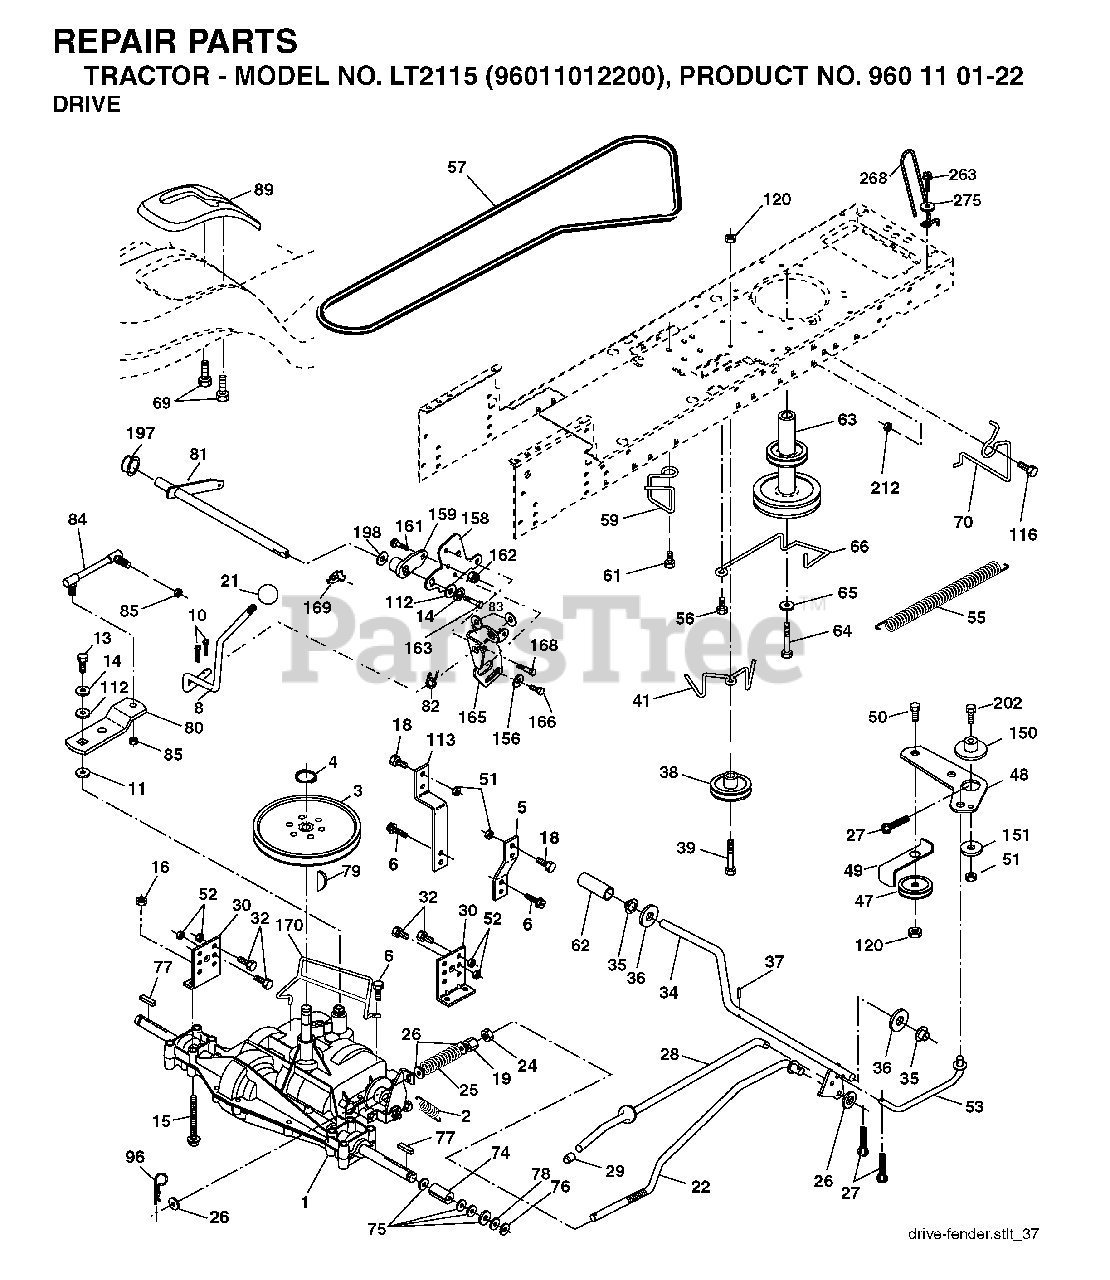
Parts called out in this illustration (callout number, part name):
2	SPRING,BRAKE RETURN
3	PULLEY TRANS
4	RETAINING RING LT
5	STRAP TORQUE
6	SCREW 5/16"
8	ROD.SHIFT.FENDER.ADJ.STLT
10	PIN COTTER
11	WASH-SHFT PLT LT
13	BOLT 1/4-28X3/4
14	LOCKWASHER
15	BOLT HEX 5/16-18 GR 5
16	NUT.71038.31-18.HEX.NYLOCK
19	NUT
21	KNOB.DUCKHEAD.1/2
22	ROD BRAKE
24	NUT
25	SPRING ROD LT
27	COTTER PIN
28	ROD, PARKING BRAKE
29	PLUNGER CAP
30	BRKT, MOUNT TRNSAXLE
32	BOLT
34	SHAFT, FOOT PEDAL
35	BEARING.NYLON
36	WASHER LT
37	DRIVE PIN
38	PULLEY IDLER COMPOSITE
41	KEEPER, BELT IDLER
47	IDLER PULLEY
48	BELLCRANK, CLUTCH
49	RETAIN BELT
50	BOLT.3/8-16X1.50
51	LOCKNUT
52	LOCKNUT
53	LINK.CLUTCH.7.66.2005
55	SPRING, RETURN LT
56	SCREW.3/8-16
57	BELT, V GROUND DRIVE 95 25
59	KEEPER, BELT CENTER
61	SCREW 3/8-16X.875
62	PEDAL COVER T
63	ENGINE PULLEY
64	BOLT HEX 7/16-20X4-1/4"
65	LOCKWASHER
66	KEEPER BELT ENGINE
69	SCREW.HI-LO.CONSOLE
70	KEEPER BELT ENG
74	SPACER AXLE
76	E-RING LT
77	SQUARE KEY
80	ARM SHIFT
82	SHIFT SPRING
83	WASHER
85	NUT LOCK CENTER 1/4 -28 FNTHD
96	RETAINER M
112	WASHER LT
113	STRAP TORQUE LH LT
116	BOLT D
120	NUT LOCK FLG 3/8-16 UNC
150	SPACER, RETAINER
151	WASHER 12/32X2X10GA
156	WASHER.SRRTD.5/16
158	BRACKET
159	HUB.SHIFT
161	BOLT
162	NUT.CROWNLOCK.1/4
165	RP BRACKET
168	BOLT.SHOULDER.5/16-18X
169	PLATE.FASTENING.CROSS.SHAFT
170	KEEPER BELT T/A
197	NYLINER SNAP 5/8" ID
198	WASHER.NYL.7/8IDX.105"HYD CR
202	BOLT
212	NUT
263	SCREW, 3/8-16X3/4
275	WASHER
